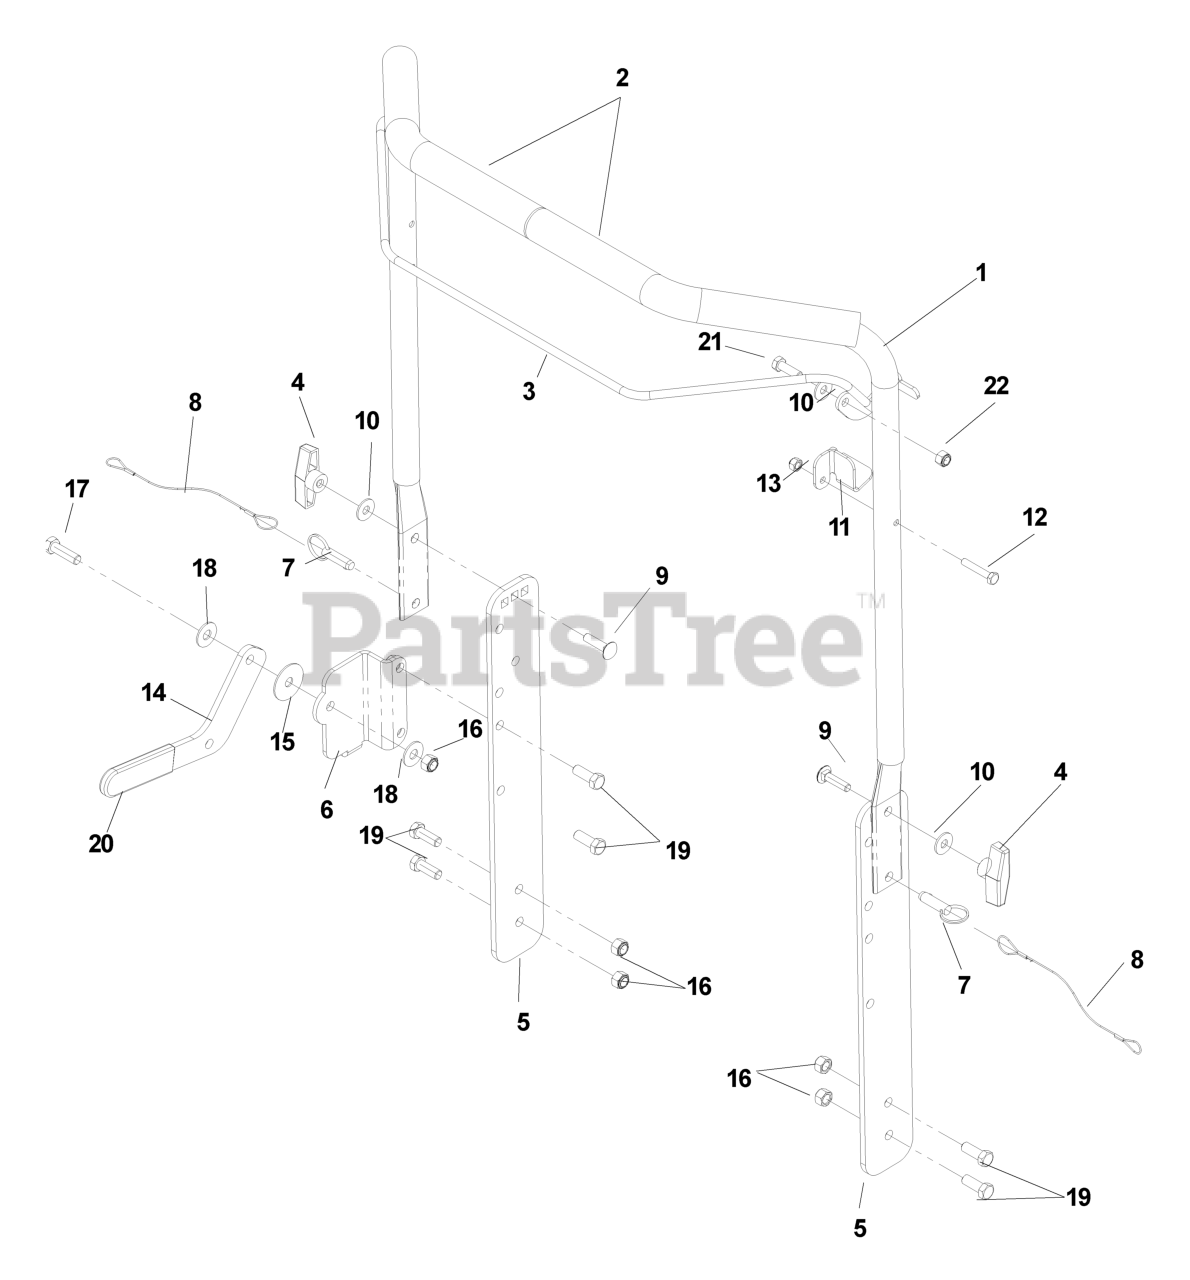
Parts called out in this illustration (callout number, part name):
1	HANDLE GRAY
3	BAIL - ORANGE
5	HANDLE SIDE GRAY
7	DETENT PIN RAKE/DT
9	BOLT, CARRIAGE 5/16X1-1/4
10	WASHER 5/16 FLAT
11	CABLE TAB POWER RAKE
12	SCW 1/4-20 X 1-1/2 HEX
13	NUT.1/4-20.HEX.NYLOC.ZD
15	WASHER, FRICTION
16	NUT 3/8-16 NYLOC
17	HCS 3/8C X 1 1/4 GR5
18	WASHER 3/8 FLAT
19	HCS 3/8-16X1.GRD.5.ZD
21	HCS 5/16C X 1
22	NUT 5/16 NYLOC
